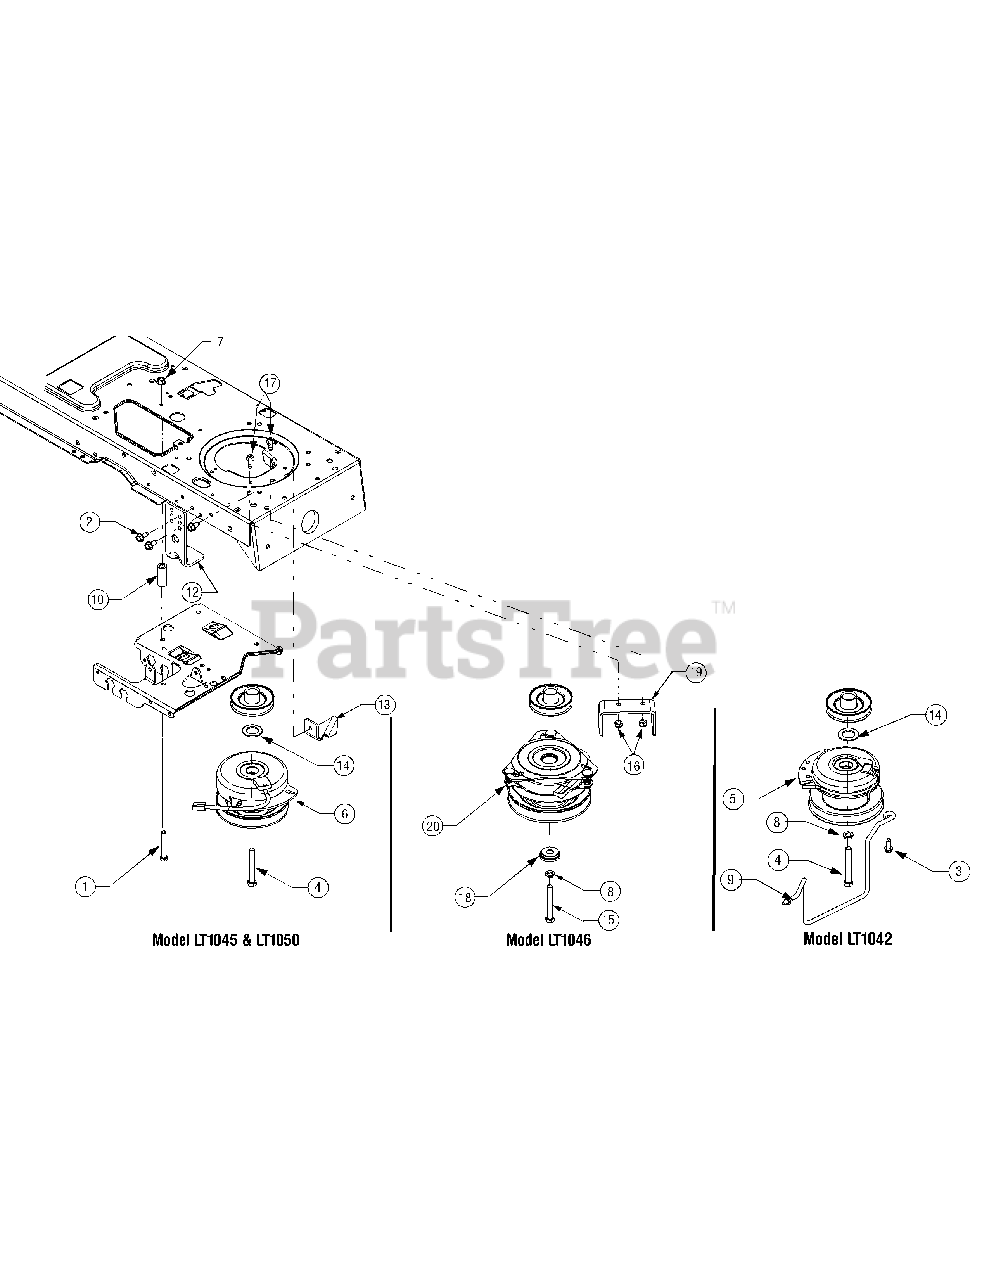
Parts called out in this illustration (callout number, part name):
1	Screw, 3/8-16 x 2.5 GR5
2	Screw, 5/16-12, .75
3	Screw, 5/16-18, .875
4	Screw, Hex Cap, 7/16-20 x 3.25 GR5
4	Screw, Hex Cap, Lock, 7/16-20 x 3.5 GR5
5	Clutch, PTO
6	Clutch, PTO
7	Nut, Hx. Nylon Lock, 3/8-16
8	Washer, Lock, 7/16, Regular Duty
9	Rod, Belt Keeper
10	Spacer, 3/8 x 1.54
11	Washer, Flat, 1.031 x 1.62 x .095
14	Washer, Flat, 1.031 x 1.62 x .095
15	Screw, Hex Cap, 7/16-20 x 2.50 GR5
16	Nut, Lock, Hex, 5/16-18
17	Screw, Hex Cap, 5/16-18 x.625 GR5
18	Shoulder Spacer, 1.38 x.445 x.36
